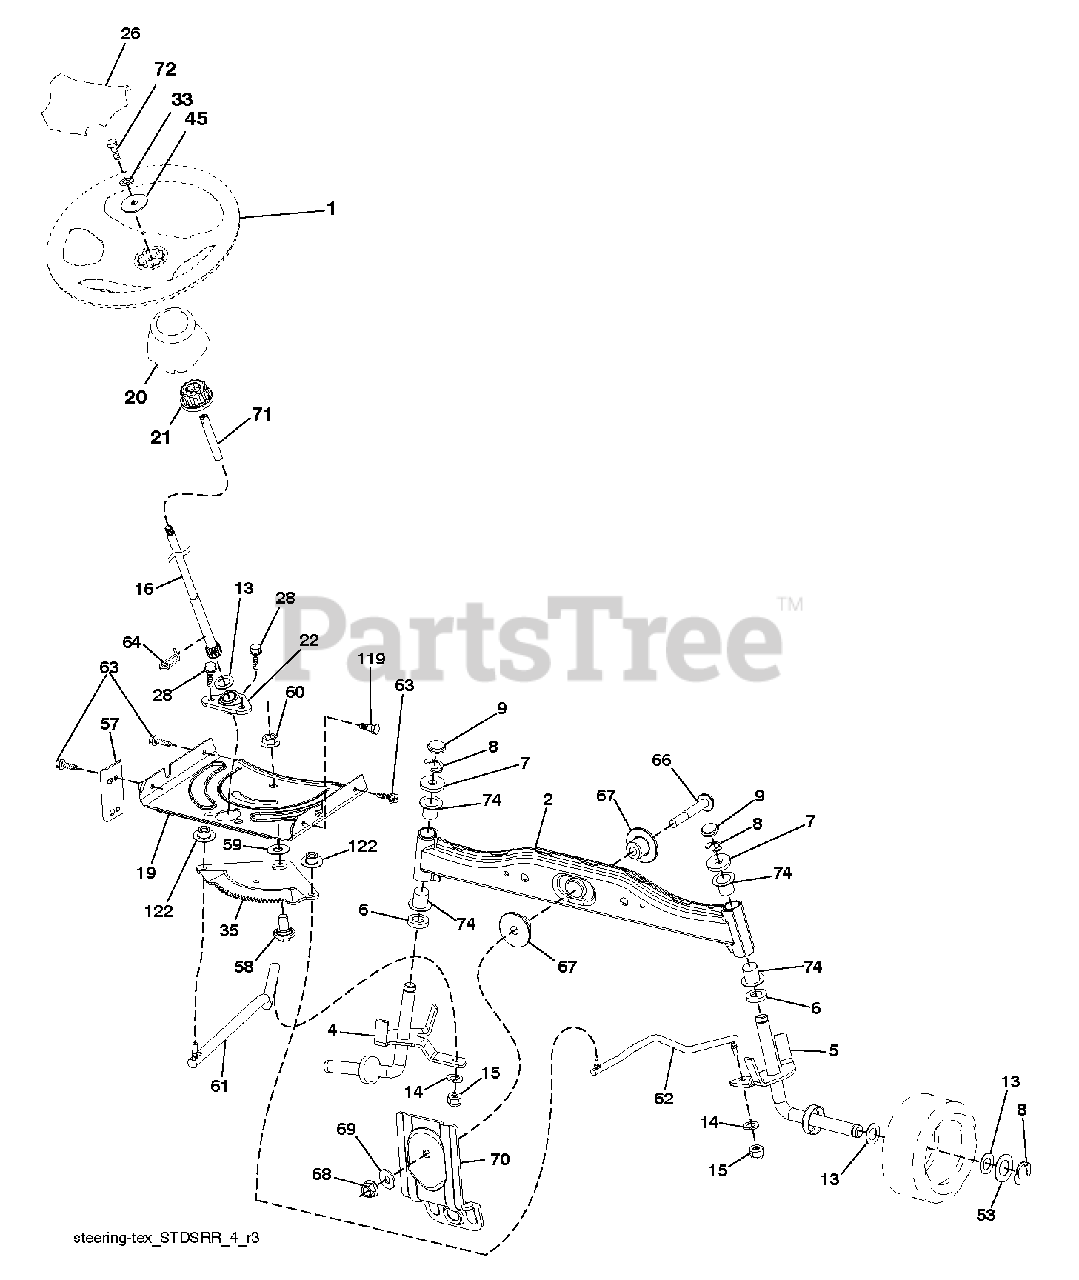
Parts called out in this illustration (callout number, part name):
1	WHEEL.STEER.HUSQ.SR.498.OVMLD
2	AXLE HALF ASM-WELDED
4	SPINDLE.STEERING.ASM.LH.13".TI
5	SPINDLE.STEERING.ASM.RH.13".TI
6	THRUST WASHER
9	CAP.SPINDLE.BLACK
14	WASHER, LOCK 3/8
15	NUT CROWNLOCK 3/8-24
16	SHAFT.STEER.3/4.PLATED.TEX
19	PLATE.STEER.DDL.NLT/NG
20	STEERING.BOOT.HUSQ.LT
21	ADAPTER, WHEEL STNG..
22	STEERING.SUPT.LOWER.
26	INSERT.CAP.WHL.STRG.HUSQ.PREM
28	SCREW, 3/8-16X3/4
33	LOCKWASHER
35	GEAR.SECTOR.PLATE.DDL.
45	WASHER.11/32
53	WASHER.HARDENED
57	BRACKET.UPSTOP.TEX
58	BOLT.SHOULDER.SECTOR.P
59	WASHER.THURST.SECTOR.S
60	NUT FLANGE LOCK 5/8-11
61	DRAGLINK.LH.BALLSTUD.D
62	DRAGLINK.RH.BALLSTUD.D
63	SCREW
64	RETAINER.CLIP.SPRING.S
66	BOLT HEX FGHD 7/16-14 X 3 SERR
67	BUSHING.PM.FRONT AXLE
68	NUT.LOCK.FLANGE.7/16
69	WASHER.1.5X.505X.118
70	BRACKET.SUSP.MWR.FRT.30"SRD
71	SHAFT.EXTEN.STRG.SPLINE
72	BOLT 5/16-18 X 4 W/PATCH
74	BRNG T
119	SHOULDER BOLT 5/16-18TT
122	CAP.GEAR.SECTOR.TEX
